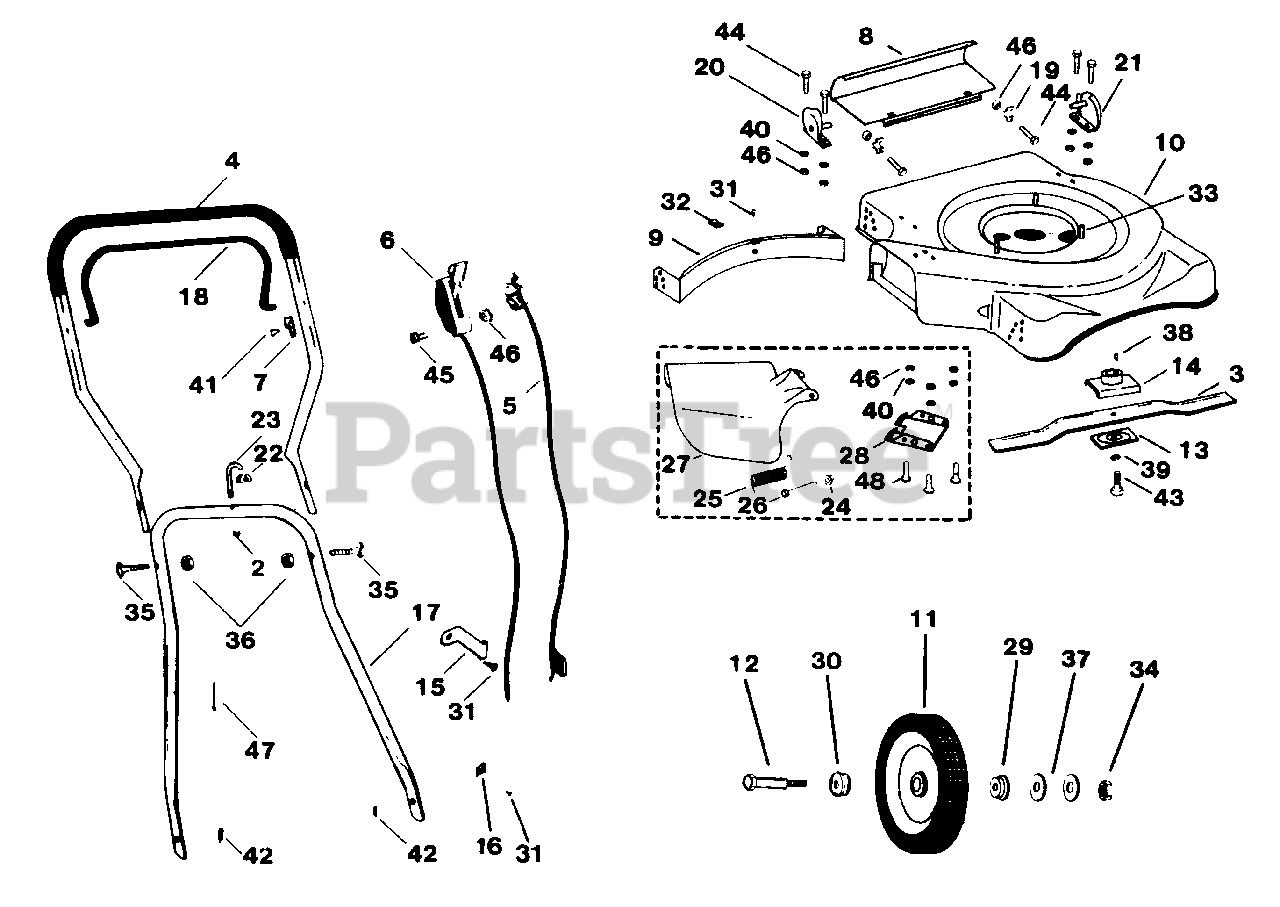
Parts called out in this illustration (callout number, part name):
2	Nut- .250-20 Keps
3	Blade-20"
4	Handle-Upper
5	Zone Restart Cable
6	Throttle Control
7	Brkt.-Bail Stop
8	Drag Guard-20"
9	Rear Band-20"
11	Wheel Ass'y.-7"
12	Shoulder Bolt
13	Retainer Plate
14	Blade Adaptor
15	Throttle Cable Guide
16	Clamp-Throttle Control
17	Handle-Lower
19	Brkt.-Drag Pin Hinge
20	Brkt-Handle-RH.
20	Decal-Be Careful (Rear top of deck)
20	Decal-Caution (On Guard)
20	Decal-Caution (By Deflector)
20	Decal-Start & Stop (on top of upper handle)
21	Brkt.-Handle-LH.
22	Rope Guide
25	Spring-Torsion
28	Hinge Bracket
29	Bearing-Inner
30	Bearing-Outer
31	Screw-#10 X .625 SEMS
32	Nut- .187 Tinnerman
33	Screw- .375-16 x 1.00 Ind. Hex HD.
34	Nut-.375-16 Keps
35	Saddle Bolt- .312-18 x 1.250
36	Nut-.312-18 Keps
37	Guard Washer
38	Key, Woodruff- .156 x .625
39	Lockwasher- .375
40	Washer- .250
41	Screw-#10-32 x .50
42	Pin, Cotter .125 x .750
43	Capscrew-Hex HD. .375-24 x 1.250
44	Capscrew-Hex HD. .250-20 x .50
45	Capscrew-Hex HD. .250-20 x 2.00
46	Nut, Lock .250-20
47	Plastic Cable Tie
48	Bolt, Carriage- .250-20 x .50
48	Decal-Danger (Side deck in Front of discharge opening)
48	Decal-20" (on front Lip of deck)
48	Decal-Simplicity (Top of deck)
